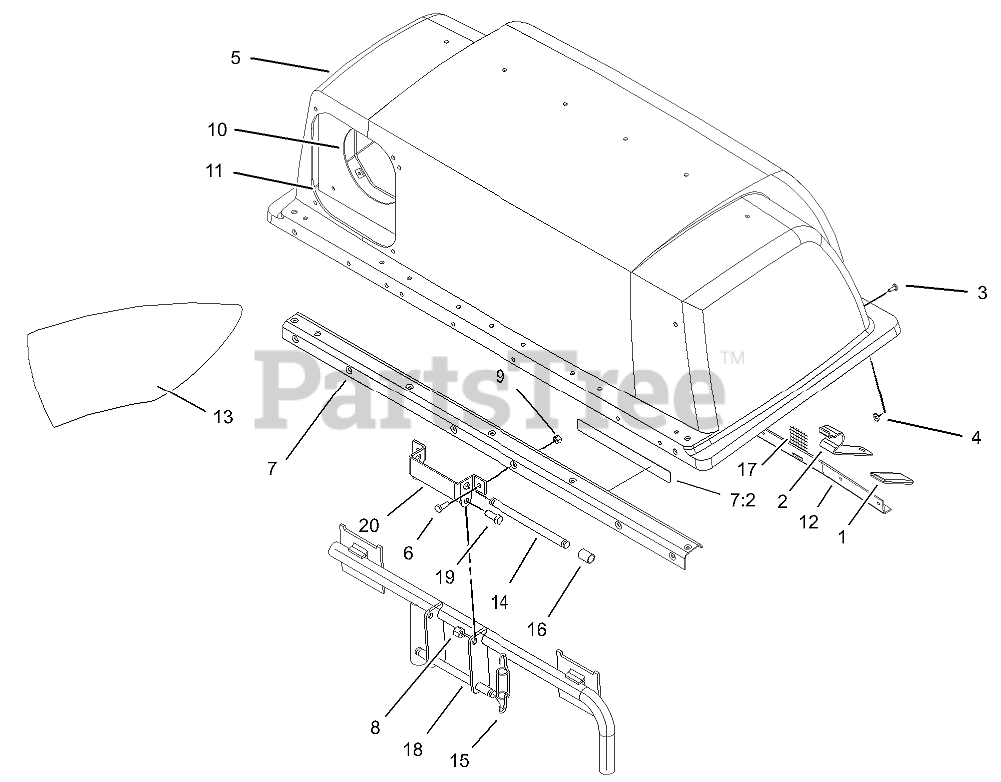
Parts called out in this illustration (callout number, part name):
2	LATCH-BAGGER, TOP
3	RIVET-BLIND
4	WASHER-FLAT
5	Top-Bagger
6	SCREW-HH
7	STIFFENER ASM
7:2	DECAL-CAUTION
8	NUT-LOCK, NI
9	NUT-LOCK, NI
10	CLAMP-SEAL
11	SEAL-CHUTE
12	SUPPORT-SCREEN
13	CHUTE-BAGGER
14	PIN-SPRING
15	SPRING-EXTENSION
16	Spacer
17	SCREEN-BAGGER
18	FRAME ASM
19	SCREW-HH
20	Hinge-Bag, Top
